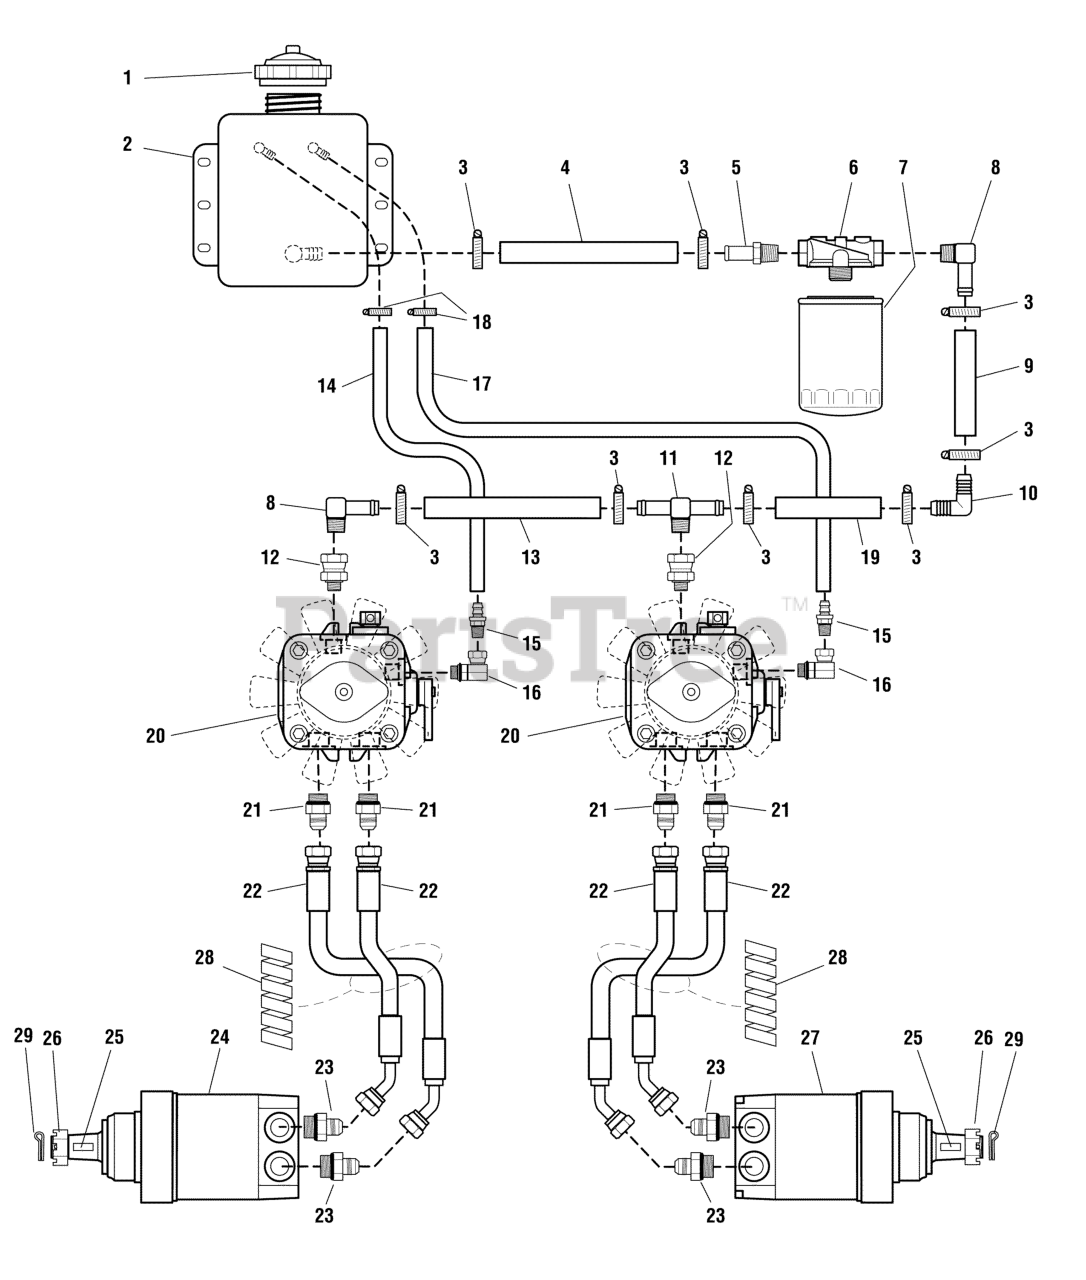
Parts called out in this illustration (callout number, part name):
1	CAP, Hydraulic Oil Only
2	KIT, TANK HYDRAULIC, 3QT W/ FITTINGS
3	CLAMP, #10 Hose
4	HOSE, Hydraulic, 11"
5	FITTING, 1/2" NPT, Straight
6	FILTER HEAD
7	FILTER, HYDRAULIC, SERVICE PART (PKG)
8	FITTING, 1/2" NPT, 90 Deg.
9	HOSE, Hydraulic, 3-1/2"
10	FITTING, 5/8", 90 Deg.
11	FITTING, 1/2" NPT, Tee
12	FITTING, Straight Swivel
13	HOSE, Hydraulic, 12"
14	HOSE, Hydraulic, 16"
15	FITTING, 1/4" NPT, Straight
16	FITTING, 9/16 O-RING - 1/4 NPT, 90 DEG
17	HOSE, Hydraulic, 24"
18	CLAMP, #6 Hose
19	HOSE, Hydraulic, 3"
20	HYDRAULIC PUMP, 10CC, w/ FAN
20	HUB & FAN KIT
21	FITTING, O-Ring Adapter
22	HOSE ASSEMBLY, (33)
23	FITTING, O-Ring Adapter
24	HYDRAULIC WHEEL MOTOR-LEFT, Complete
25	KEY
26	NUT, CASTLE, 1-20
27	HYDRAULIC WHEEL MOTOR-RIGHT, Complete
28	PROTECTIVE COIL, 12"
29	PIN, COTTER, 1/8" X 2"
